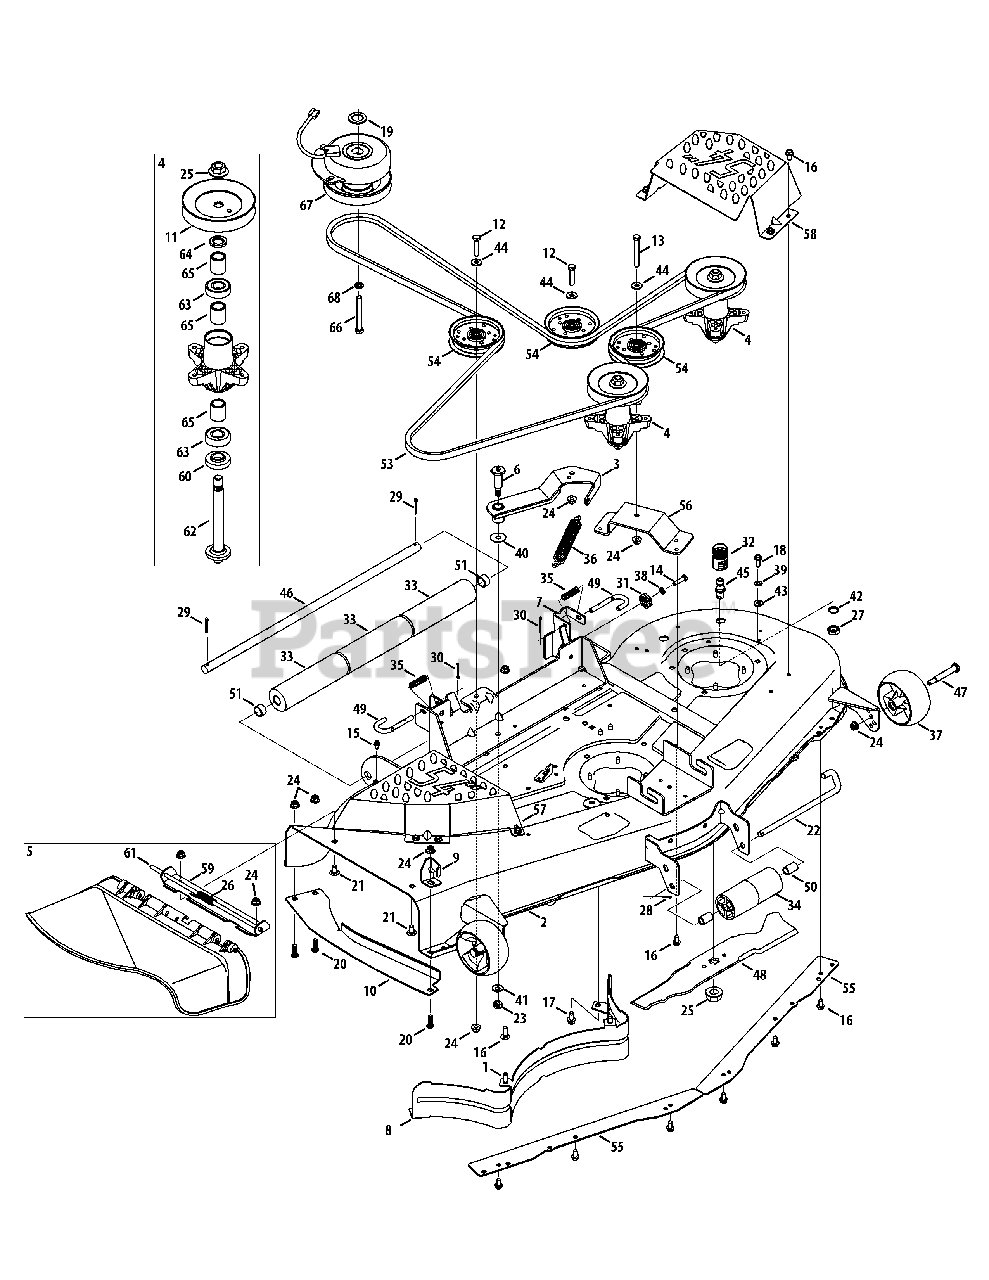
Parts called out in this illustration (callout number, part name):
1	Carriage Screw, 3/8-16 x 1.00
4	Spindle Assembly
5	Discharge Chute Assembly
6	Shoulder Bolt Assembly
10	Finger Guard
11	V-Type Pulley, 5.39
12	Hex Cap Screw, 3/8-16 x 1.75
13	Hex Cap Screw, 3/8-16 x 3.0
14	Hex Cap Screw, 5/16-18 x 1.25
15	Hex Washer Screw, 1/4-20 x .5
16	Hex Washer Screw, 5/16-18 x .750
17	Hex Washer Screw, 3/8-16 x .75
18	Hex Washer Screw, 5/16-18 x .875
19	Flat Washer, 1.031 x 1.620 x .095
20	Hex Screw, 3/8-16 x 1.00
21	Carriage Screw, 3/8-16 x .75
22	Roller Pin, .5 x 10.06
23	Hex Lock Nut, 7/16-14
24	Hex Insert Flange Lock Nut, 3/8-16
25	Hex Flange Nut, 5/8-18
26	Torsion Spring, .44 ID x 2.00
27	Hex Nut, M16-1.5
28	Cotter Pin, 3/32 x 1.0
29	Cotter Pin, 5/32 x 1.25
30	Cotter Pin, 1/8 x 1.25
31	Deck Adjustment Gear
32	Water Nozzle Adapter
33	Deck Roller, 7.895
34	Front Roller
35	Compression Spring, .535 x 1.751
36	Extension Spring, .94 x .04609
37	Deck Ball Wheel, 5.0
38	Lock Washer, 5/16
39	Flat Washer, .344 x .688 x .065
40	Flat Washer, .442 x 1.39 x .06
41	Bell Washer, .45 x 1.0 x .062
42	Lock Washer
43	Flat Washer, .407 x .812 x .135
44	Flat Washer, .38 x .93 x .110
45	Deck Wash Nozzle
46	Shaft, .75 x 26.893
47	Shoulder Screw, .5 x 2.5 x 3/8-16
48	Blade, 18.5
49	Deck Hanger Rod
50	Spacer, .55 x .75 x 1.125
51	Spacer, .82 x 1.0 x.53
52	Spacer, .38 x .9 x 1.313
54	Idler Pulley, 4.25 Dia
59	Chute Mounting Bracket
60	Spacer, .79 x 1.82 x .55
62	Spindle Shaft, 6.95
63	Ball Bearing
64	Spacer, .79 x 1.25 x .175
65	Spacer, .80 x 1.10 x 1.32
66	Screw, 7/16-20 x 3.50
67	Electric PTO Clutch
68	Lock Washer, 7/16
